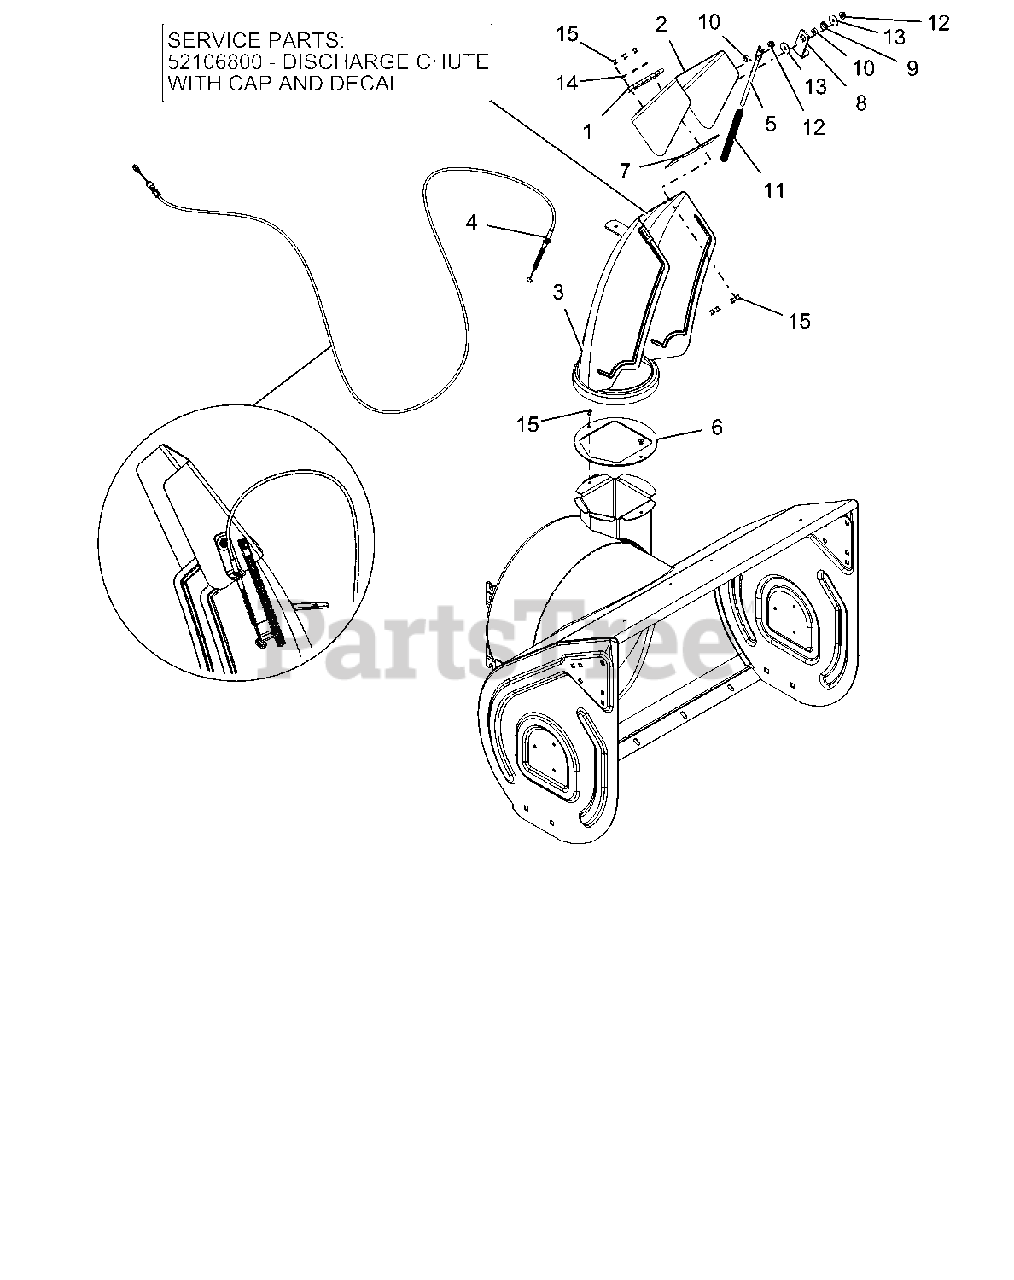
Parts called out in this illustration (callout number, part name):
2	CAP,LARGE,REMOTE
3	CHUTE,DISCHARGE,NOTCHED,QT
4	CABLE, DEFLECTOR - DELUXE
5	ROD, DEFLECTOR CAP
6	BAFFLE, DISCHARGE NECK
7	CAP SEAL 5.50
7	KIT, DISCHARGE CHUTE W/DEF QT2
8	BRACKET, CABLE ANCHOR
9	BUSHING, POLYLINER-.50 SNAPIN
10	BSHG-SLV .265X.500X.219
11	SG-COMP .08X.40X6.50 14#/IN
12	@NUT-LK-CTR-FLG .25-20 YWZC
13	WSHR-FL-STL .281X1.000X.063
14	WSHR-FL-STL .196X.500X.06 YZ
15	RVT-POP .187 YZ
